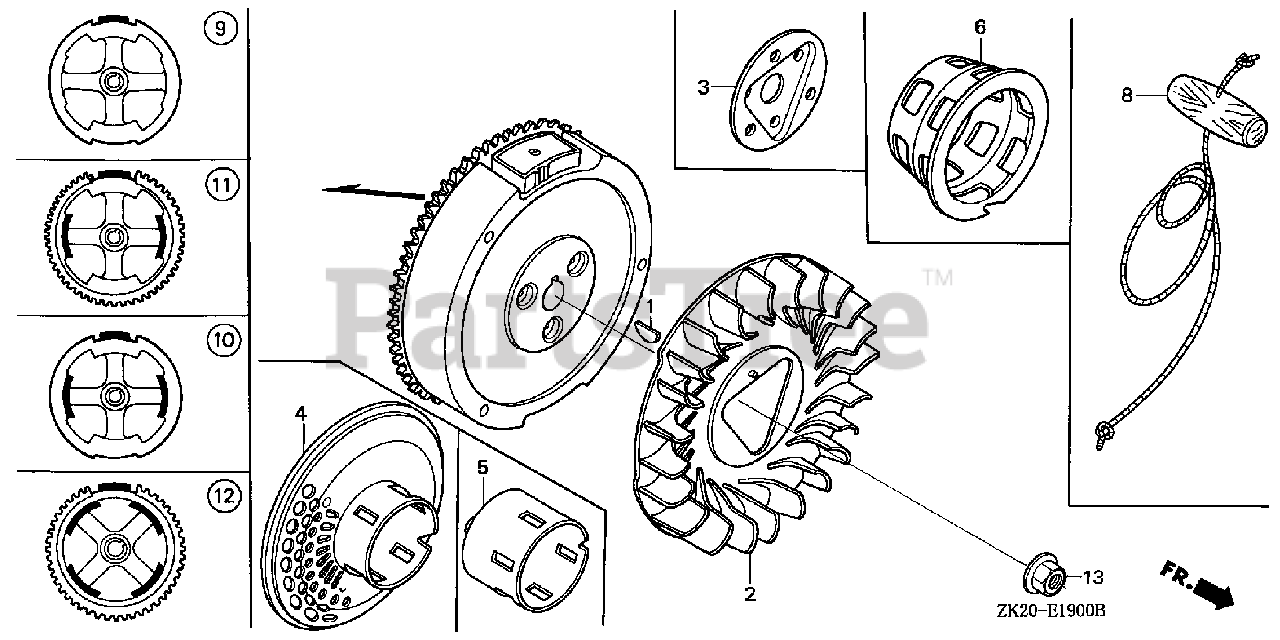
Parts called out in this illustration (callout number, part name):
1	KEY, SPECIAL WOODRUFF (25X18)
2	FAN, COOLING
5	PULLEY, STARTER
9	FLYWHEEL
13	NUT, SPECIAL (16MM) (1)
